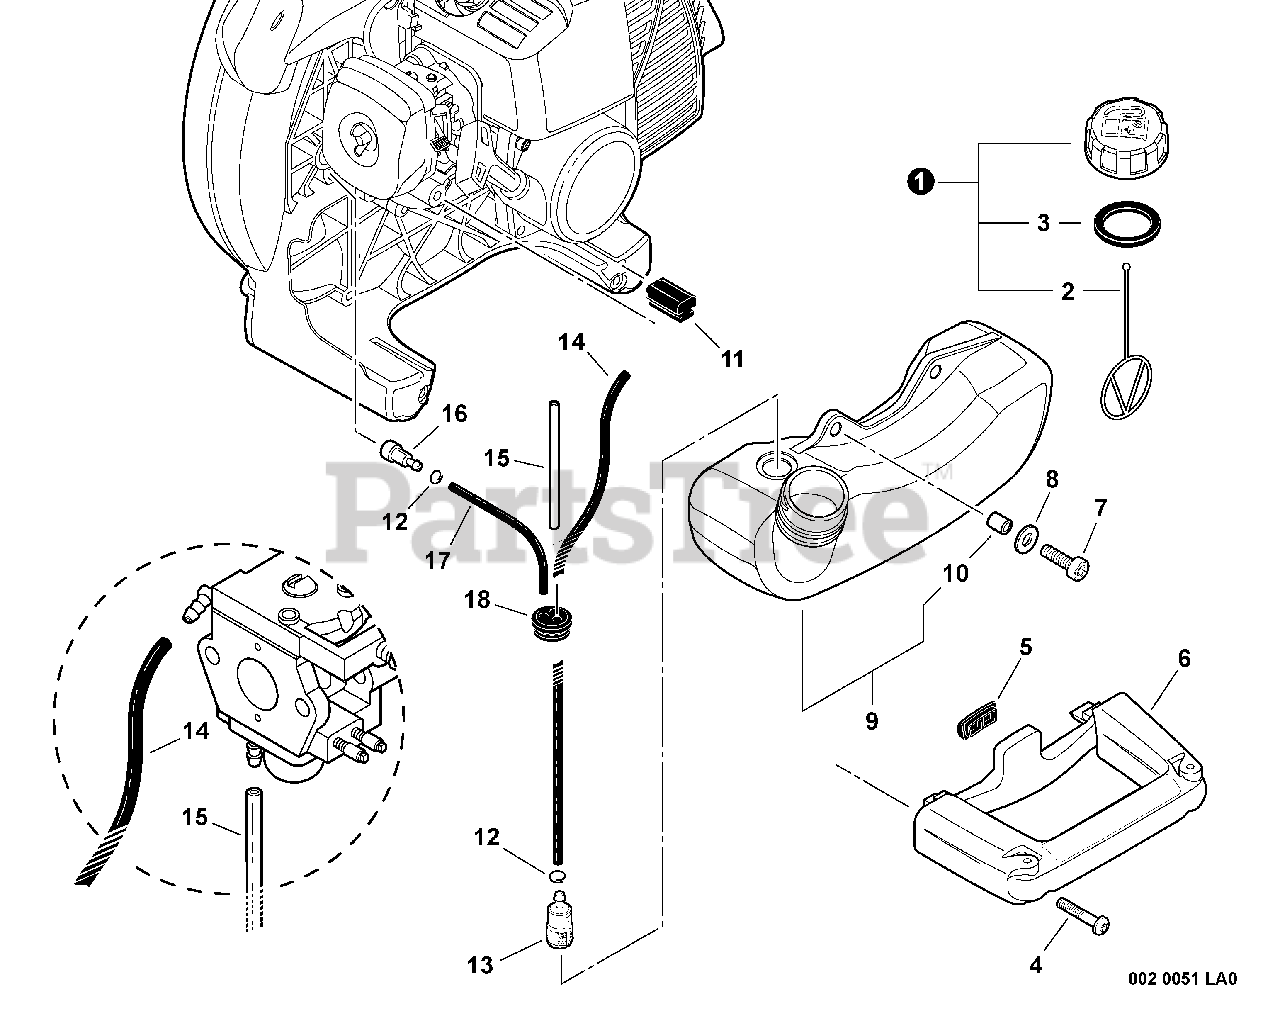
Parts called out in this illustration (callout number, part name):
1	CAP ASSY - ORANGE
2	CONNECTOR, CAP
3	GASKET, CAP
4	SCREW - 5X25
5	CUSHION
6	HANDLE - SIDE
7	SCREW - 5X16
8	WASHER - 5
9	FUEL TANK ASSY
12	CLIP - 6
13	FILTER, FUEL
14	PIPE - 3X5X210 -- BLACK
15	PIPE - 3X6X85 -- CLEAR
16	VENT, FUEL TANK
17	PIPE - 3X6X80 -- BLACK
18	GROMMET
